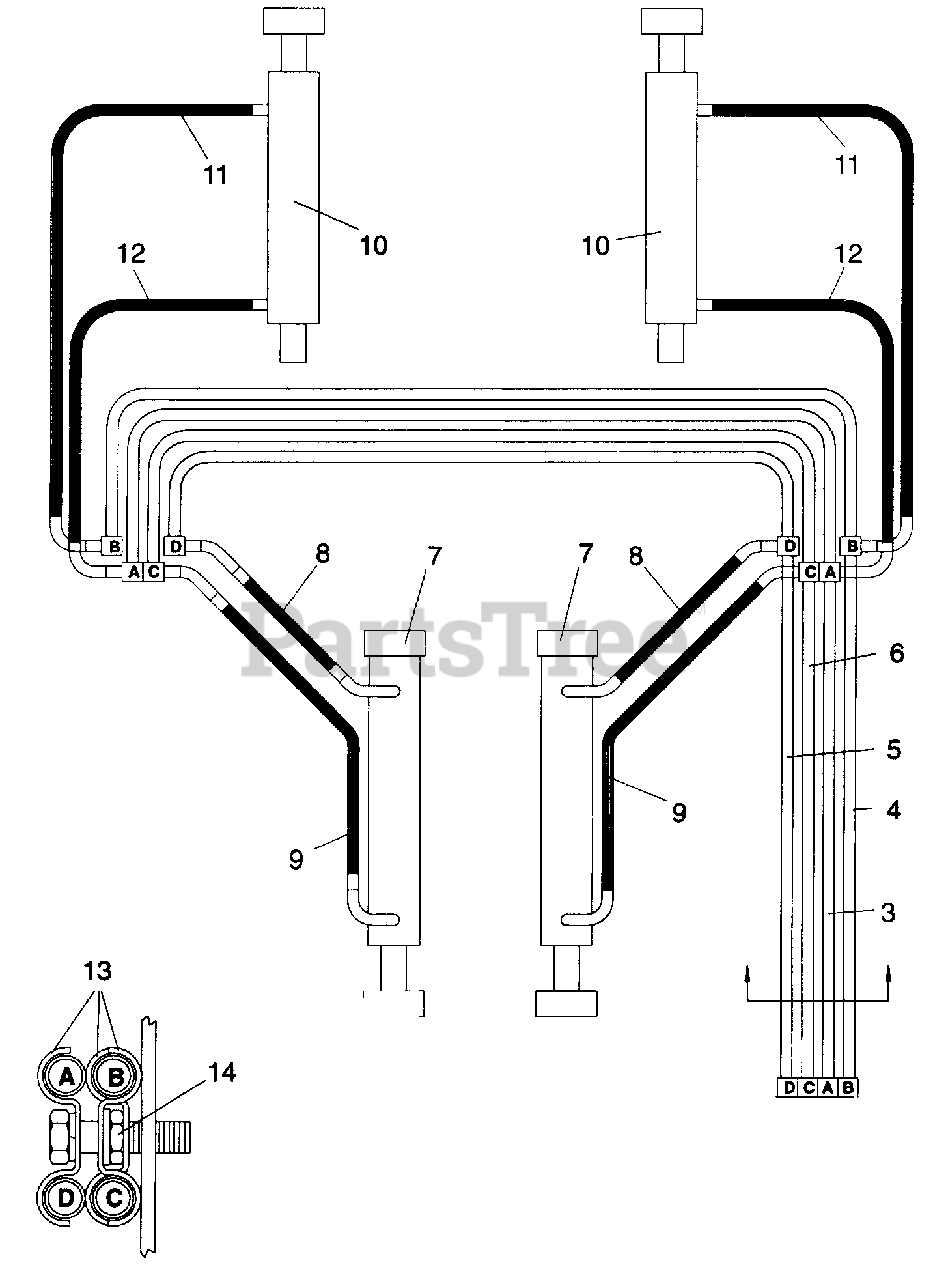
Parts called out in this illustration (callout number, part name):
3	Feedline #1
4	Feedline #2
5	Feedline #3
6	Feedline #4
7	Lift Cylinder
8	Hydraulic Hose
9	Hydraulic Hose
10	Tilt Cylinder
11	Hydraulic Hose
12	Hydraulic Hose
13	Feedline Clamp
14	Tab Weld Nut - 5/16 NC
